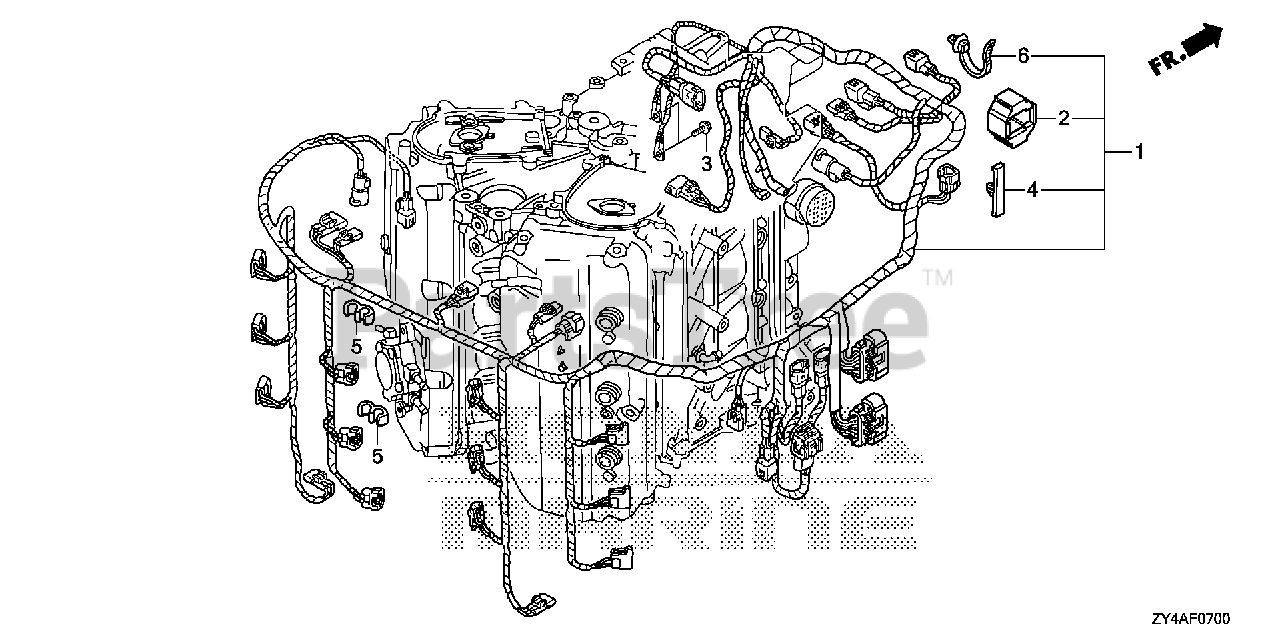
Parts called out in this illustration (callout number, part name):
1	WIRE HARNESS ASSY., MAIN
2	SUSPENSION, CONNECTOR
3	BOLT, FLANGE (6X12)
4	CLIP, WIRE HARNESS
5	CLIP A, HARNESS
6	CLIP, HARNESS BAND (145MM) (BLACK)
